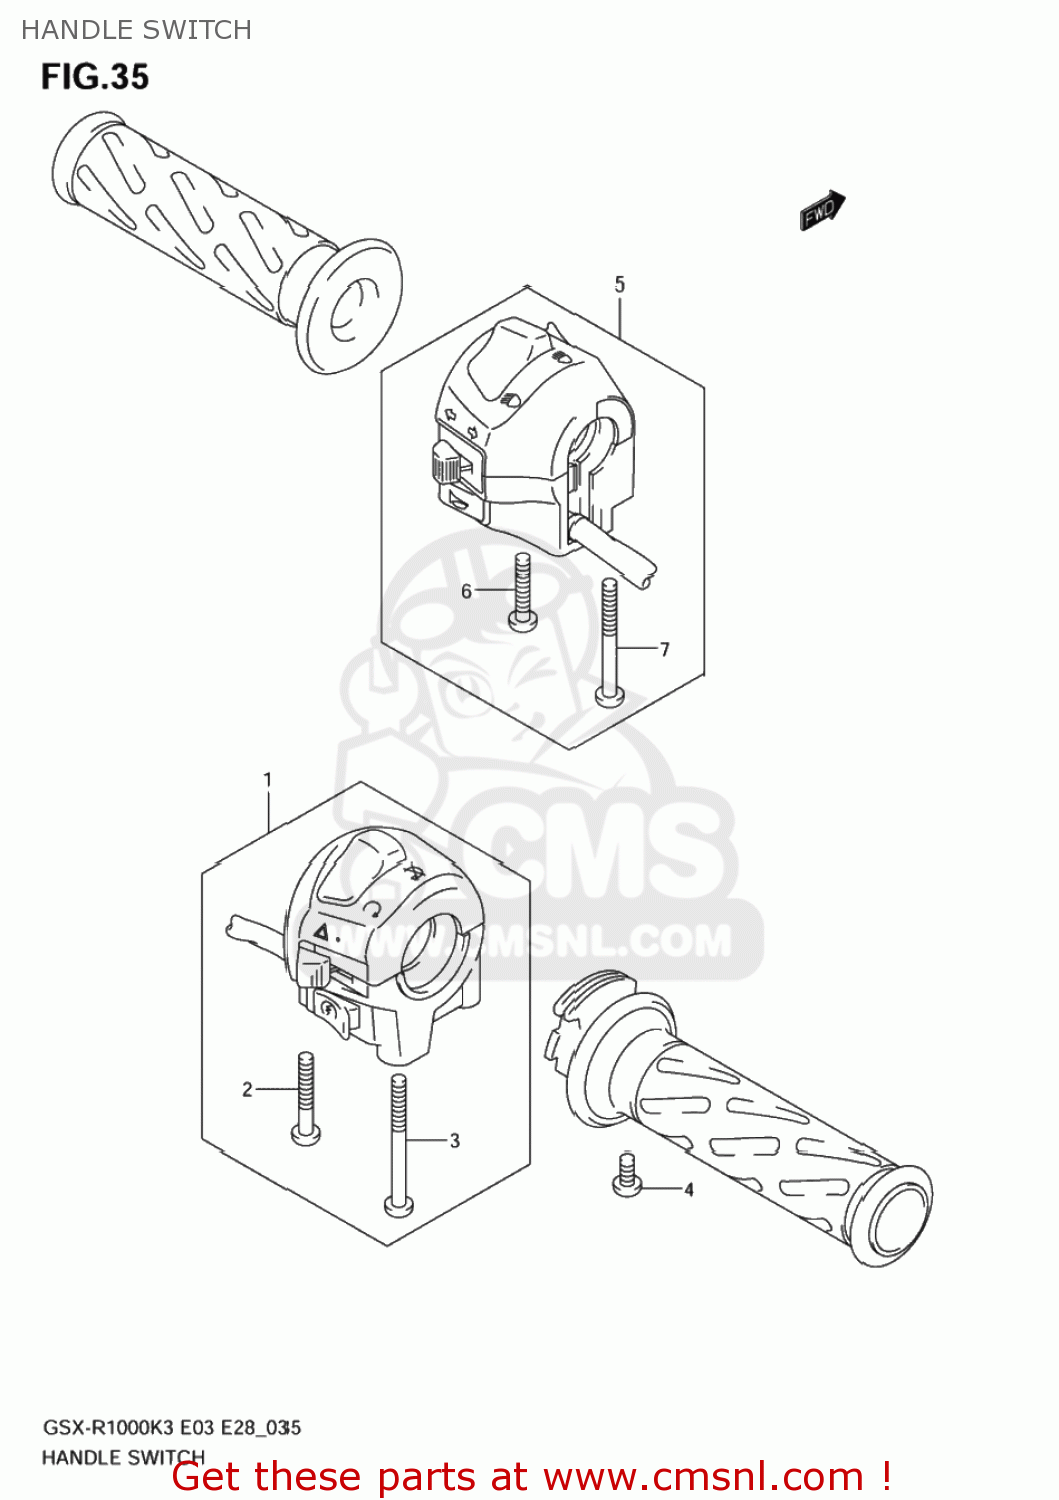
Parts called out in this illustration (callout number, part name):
1	SWITCH ASSY,HANDLE,R
2	SCREW
3	SCREW
4	SCREW
5	SWITCH ASSY,HANDLE,L
6	SCREW
7	SCREW, 5X45
